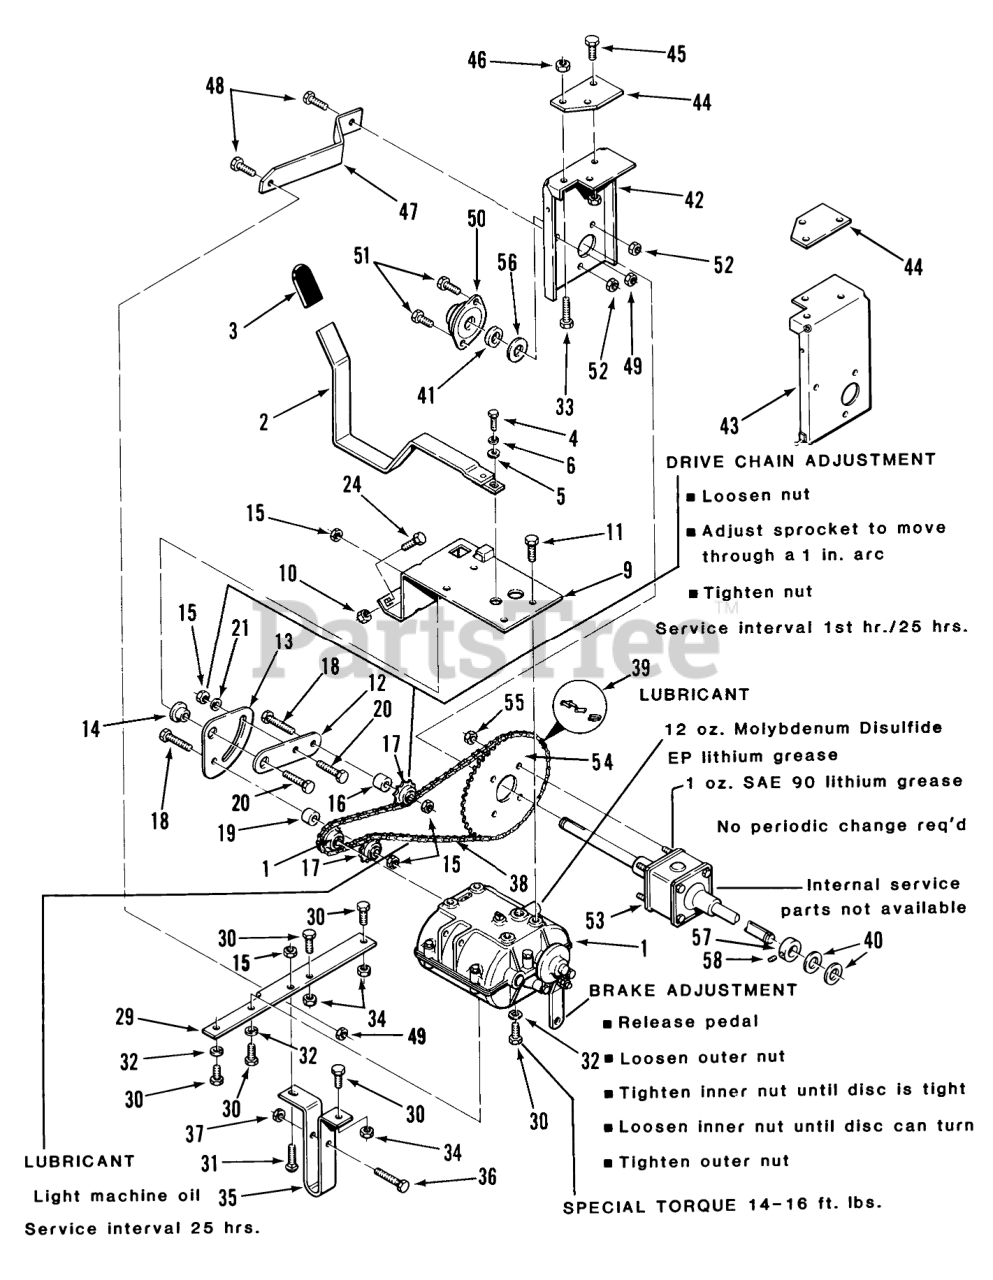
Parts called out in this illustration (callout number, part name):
1	Transmission-Peerless Mod 724A
2	Shift Lever
4	Bolt 1/4-28 X 7/8
5	WASHER
6	Washer
9	Idler Support
10	Nut
11	Screw
12	Plate-Upper Idler
13	Plate-Lower Idler
14	SPACER-BUSHING
15	Nut
16	SPACER-SPROCKET
17	IDLER-SPROCKET
18	Bolt
19	SPACER
20	BOLT HEX SPECIAL
21	Washer
24	Bolt
29	Washer-Thrust
30	Bolt
31	Bolt
32	Lockwasher
33	Bolt
34	Nut
35	Mower Guide
36	Bolt
37	Nut
38	CHAIN-ROLLER
39	MASTER LINK CHAIN
40	WASHER
41	Spacer
42	Rear Axle Bracket RH
43	Rear Axle Bracket LH
44	Plate Rear Axle Support
45	Bolt
46	Nut
47	Brace-Rear Axle Bracket RH
48	Bolt
49	Nut
50	BEARING-SIDE FLANGE
51	Bolt
52	Nut
53	ASSY-DIFFERENTIAL
54	SPROCKET
55	Nut
56	WASHER
57	Collar
58	SCREW-SET
